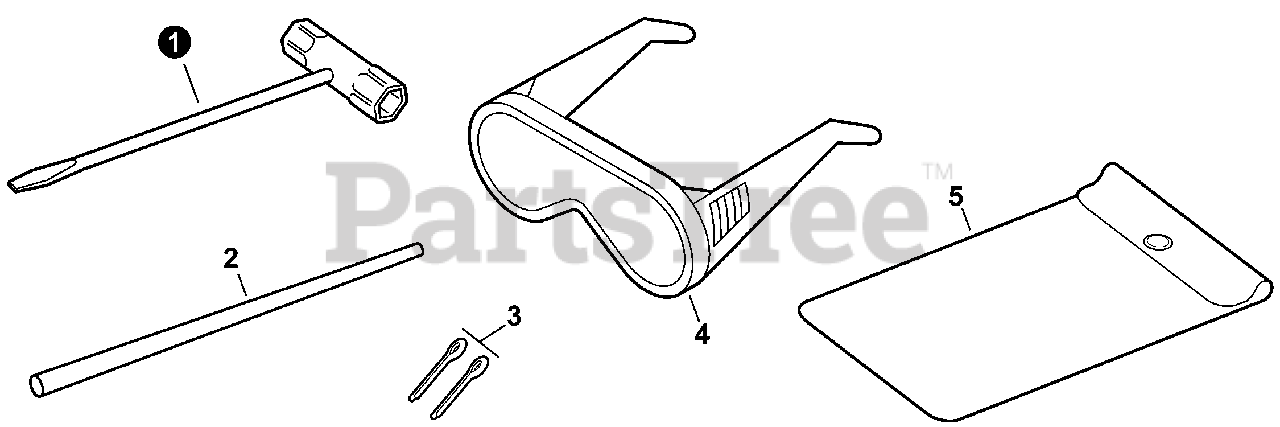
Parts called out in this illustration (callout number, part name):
1	WRENCH, T 17×19 MM
2	TOOL, LOCKING 5×120 MM
3	PIN, COTTER 2×22
4	GLASSES, SAFETY
5	BAG, TOOL
